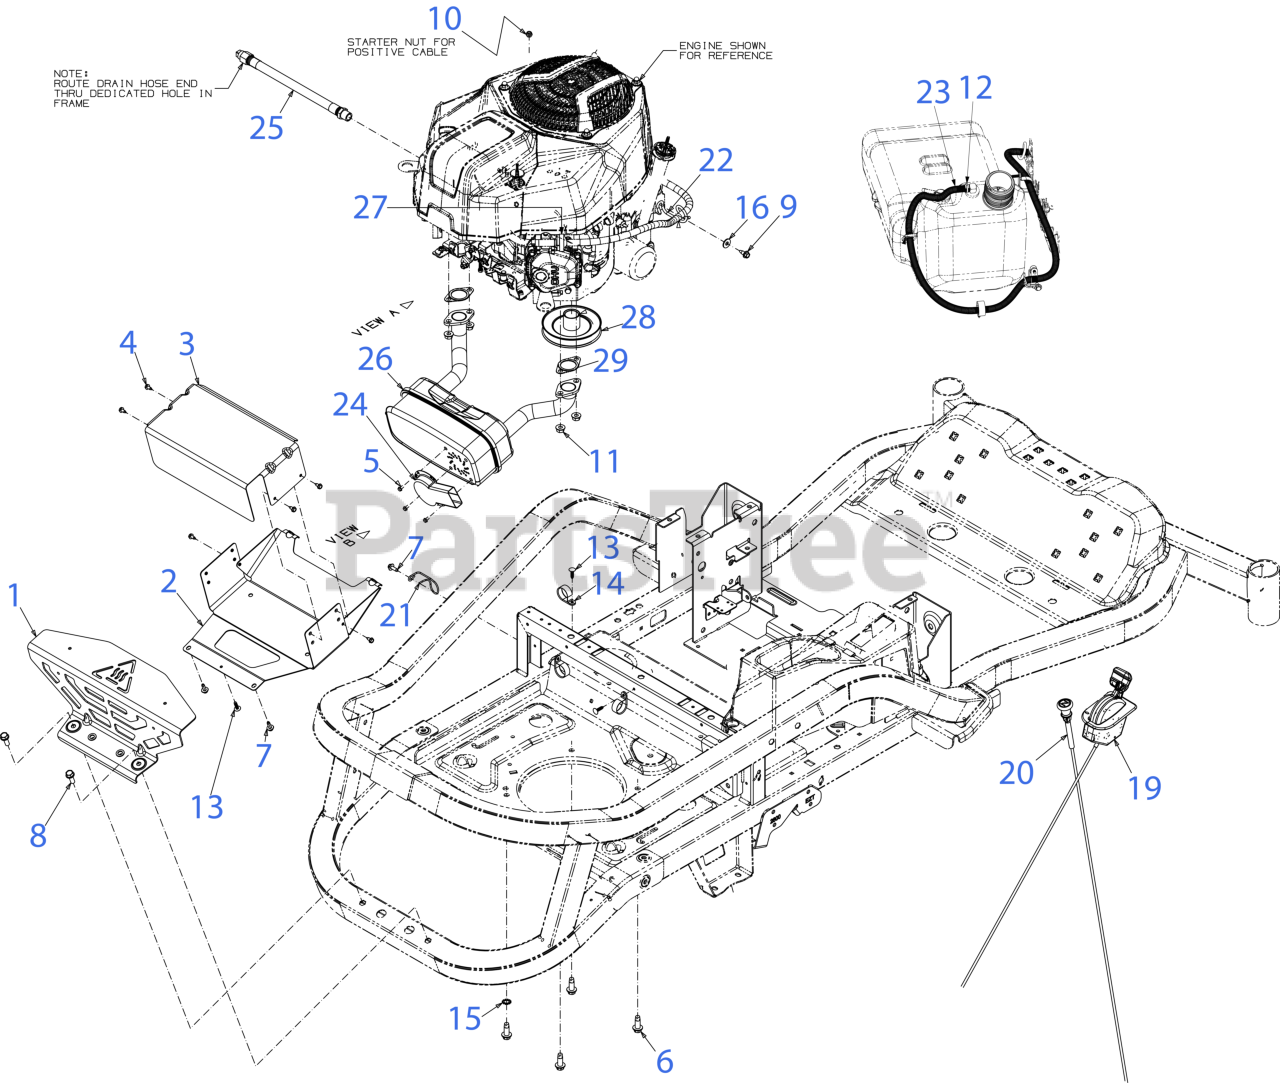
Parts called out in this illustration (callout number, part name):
1	MUFFLER COVER (REAR) (BLACK)
2	MUFFLER SHIELD (LOWER)
3	MUFFLER SHIELD (TOP)
4	HEX SCREW AB-TAP #10 x .50
5	HEX SCREW WASHER HD #8-18 x 0.500
6	SCREW 3/8-16 x 1
7	SCREW M6-1 x .625
8	SCREW 5/16-18 x .875 GR5
9	SCREW 1/4-20X.625
11	HEX FLANGE NUT M8X
12	HOSE CLAMP 1/20
13	RATCHET CLIP (.188 x .85)
14	DRAIN HOSE CLAMP
15	LOCK WASHER 3/8
16	FLAT WASHER .28 ID x .74 OD x .063
19	THROTTLE CABLE 52.5LG
20	CHOKE CABLE 51.5LG
21	HOSE GUIDE
22	HOSE GUIDE
23	FUEL HOSE LOW PERMEATION 45"
24	EXHAUST DELECTOR (LONG)
25	OIL DRAIN HOSE (11.26" 3/8 NPT)
26	MUFFLER
27	FUEL FILTER
28	TRANSMISSION DRIVE PULLEY
29	EXHAUST GASKET
